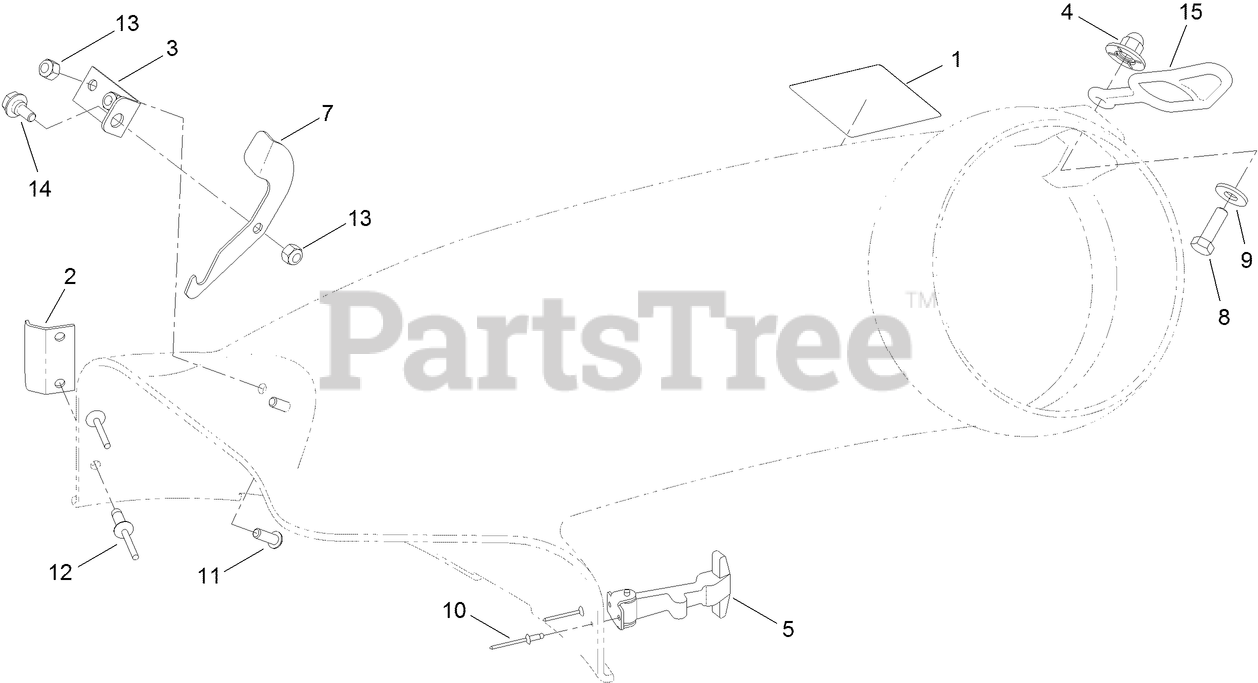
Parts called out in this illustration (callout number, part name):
1	DECAL-DANGER
2	BRACKET-ELBOW
3	PLATE-PIVOT
4	NUT-IMPELLER
5	HANDLE ASM
8	SCREW-HH
9	WASHER-FLAT
10	RIVET-POP
11	SCREW-HSBH
12	RIVET-BLIND
13	NUT-LOCK, NI
14	SCREW
15	RETAINER-DUCT
